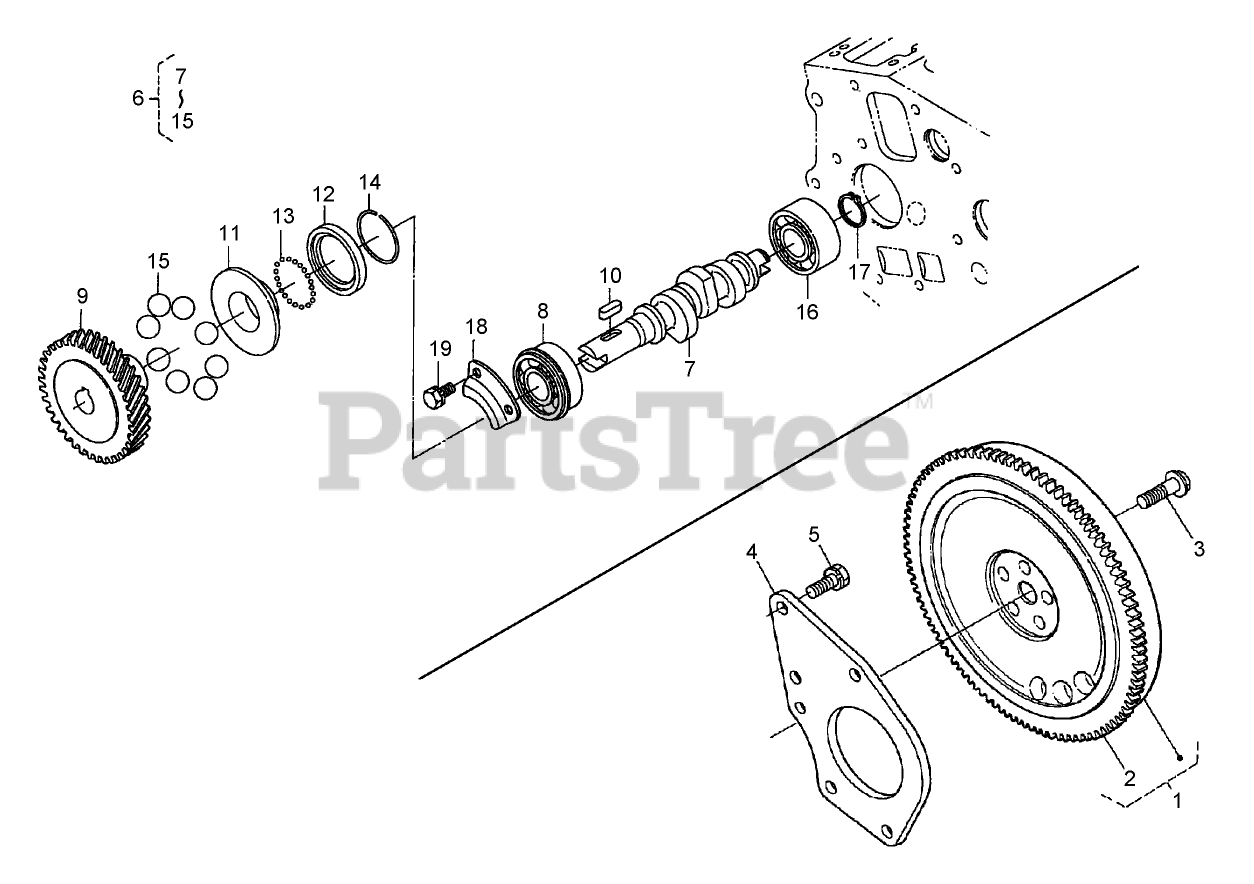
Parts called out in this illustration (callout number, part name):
1	FLYWHEEL
2	GEAR-RING
3	BOLT-FLYWHEEL
4	PLATE-END, REAR
6	FUEL CAMSHAFT ASM
7	CAMSHAFT-FUEL
8	BEARING-BALL
9	GEAR-PUMP, INJECTION
10	KEY-FEATHER
11	SLEEVE-GOVERNOR
12	CASE-BALL, GOVERNOR
14	CIRC-CLIP
16	BEARING-BALL
17	CIRC-CLIP, EXTERNAL
18	STOPPER-FUEL, CAMSHAFT
